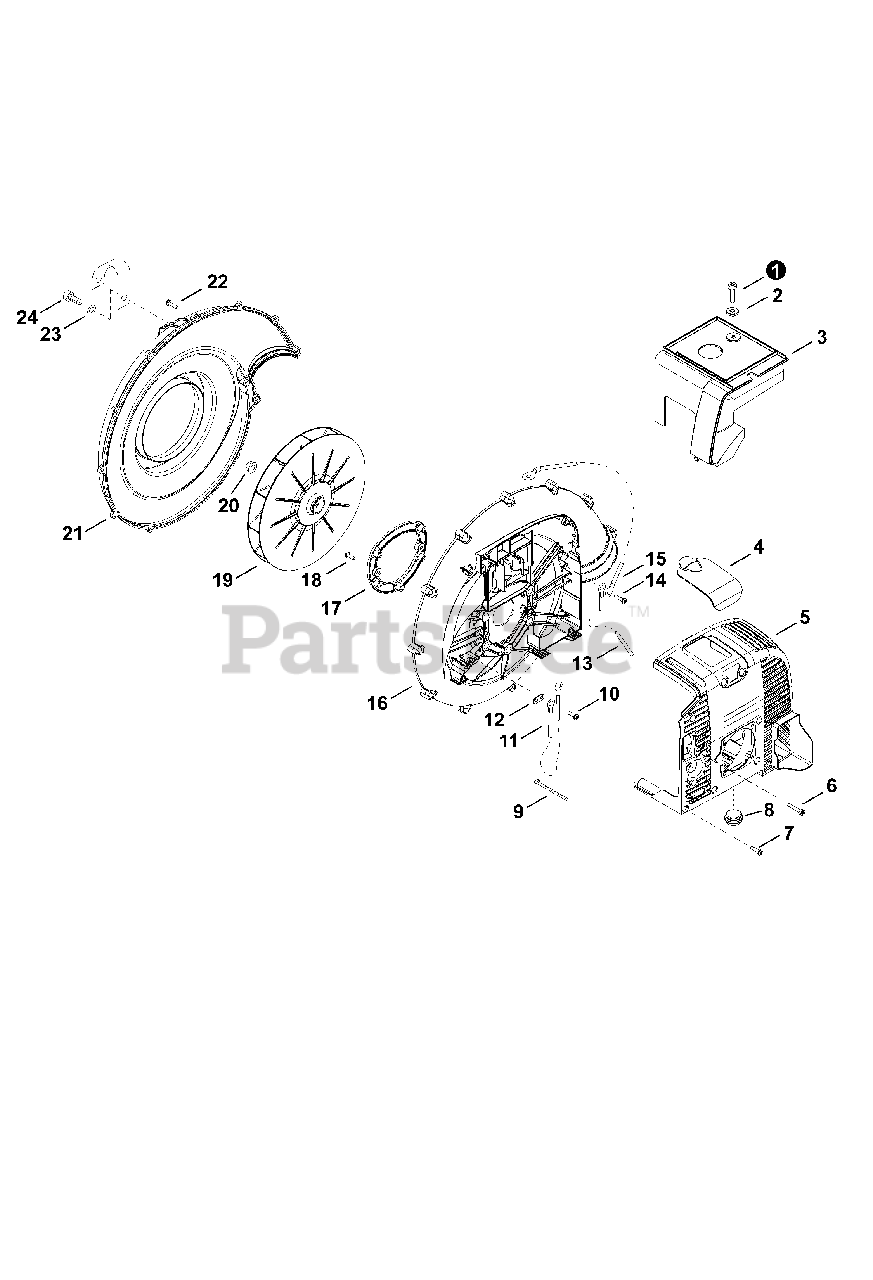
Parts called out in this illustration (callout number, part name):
1	SCREW - 5×20
2	WASHER - 5
3	COVER, CYLINDER
4	COVER, SPARK PLUG
5	COVER, ENGINE
6	SCREW - 5×16
7	SCREW - 5×20
8	CUSHION
9	TIE, CABLE - SMALL
10	SCREW - 5×16
11	LEAD - GROUND
13	LEAD - STATIC DISCHARGE
14	SCREW - 5×12
15	LEAD - GROUND
16	CASE, FAN
17	PLATE, ENGINE
18	SCREW - 5×16
19	FAN
20	NUT - 10 -- FLANGE
21	COVER, FAN
22	SCREW - 5×20
23	WASHER - 5
24	SCREW - 5×20
